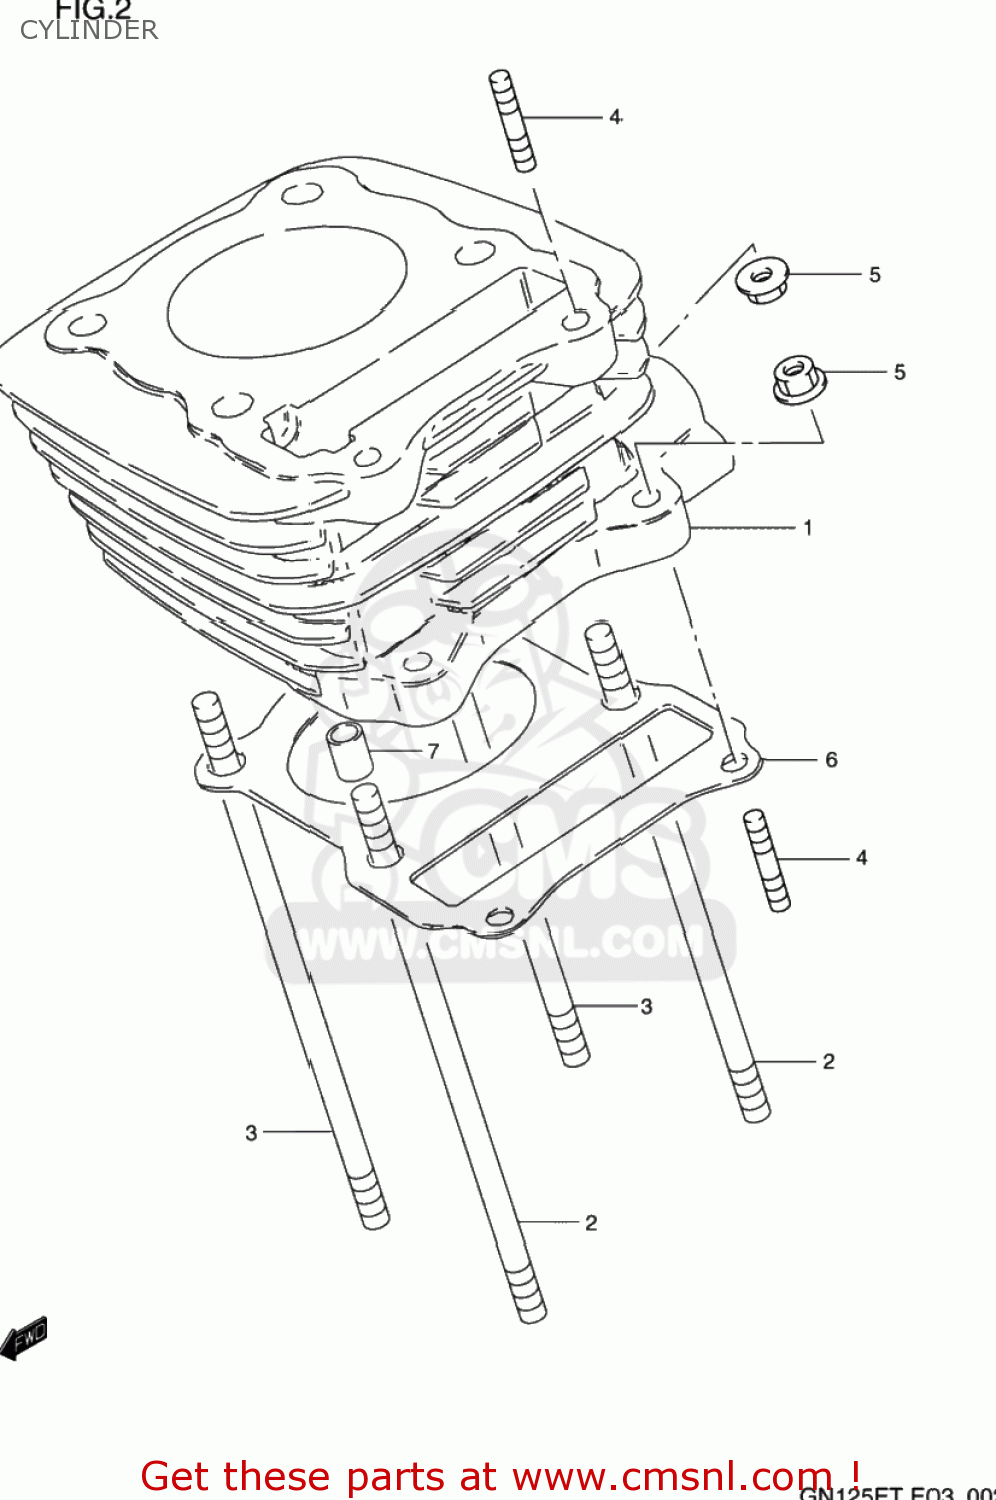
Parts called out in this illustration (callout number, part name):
1	CYLINDER
2	BOLT,STUD
3	BOLT,STUD
4	BOLT,STUD
5	NUT
6	GASKET,CYLINDER (NAS)
7	PIN
